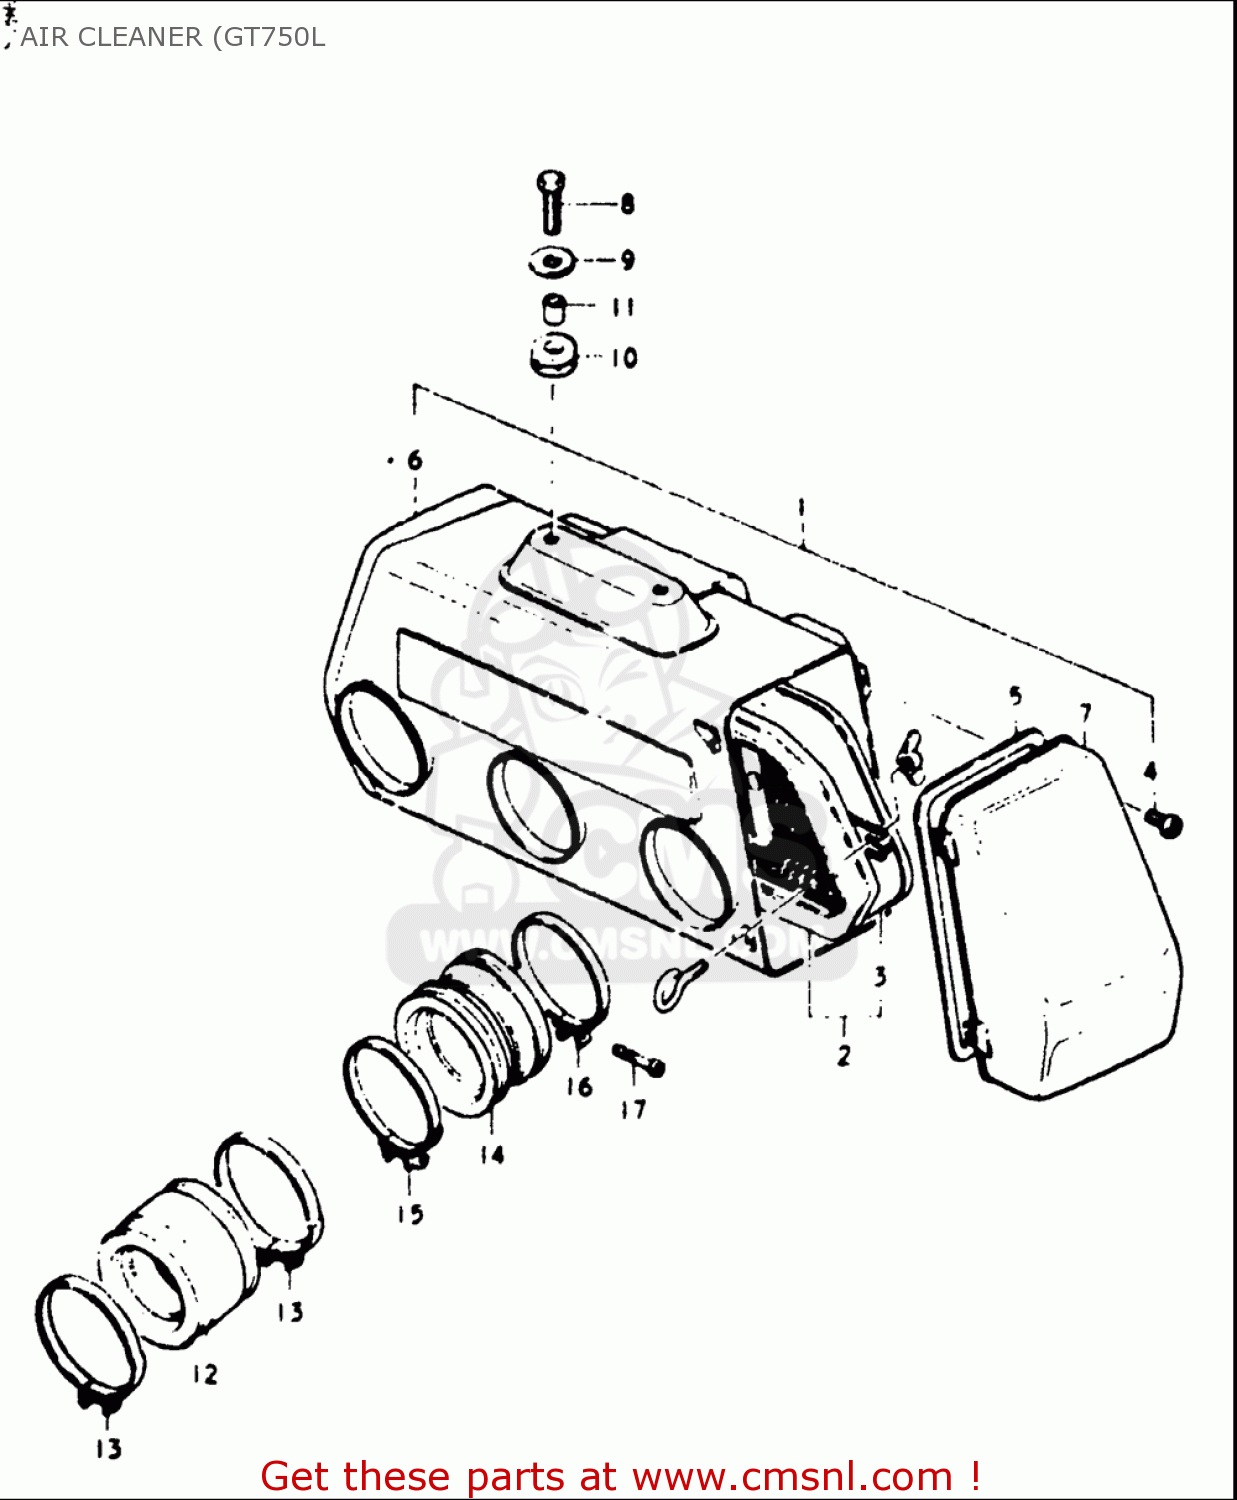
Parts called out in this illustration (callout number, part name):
2	FILTER ASSY,AIR CLEANER
3	FILTER ASSY,AIR CLEANER
4	SCREW
6	COVER,AIR CLEANER,R
7	FILTER
8	BOLT
9	WASHER(6.5X20X1.2)
10	CUSHION
11	SPACER,6.5X9X7
12	PIPE,INTAKE
13	CLAMP
14	HOSE,CARBURETOR AIR INLET
15	CLAMP
16	CLAMP
17	SCREW
